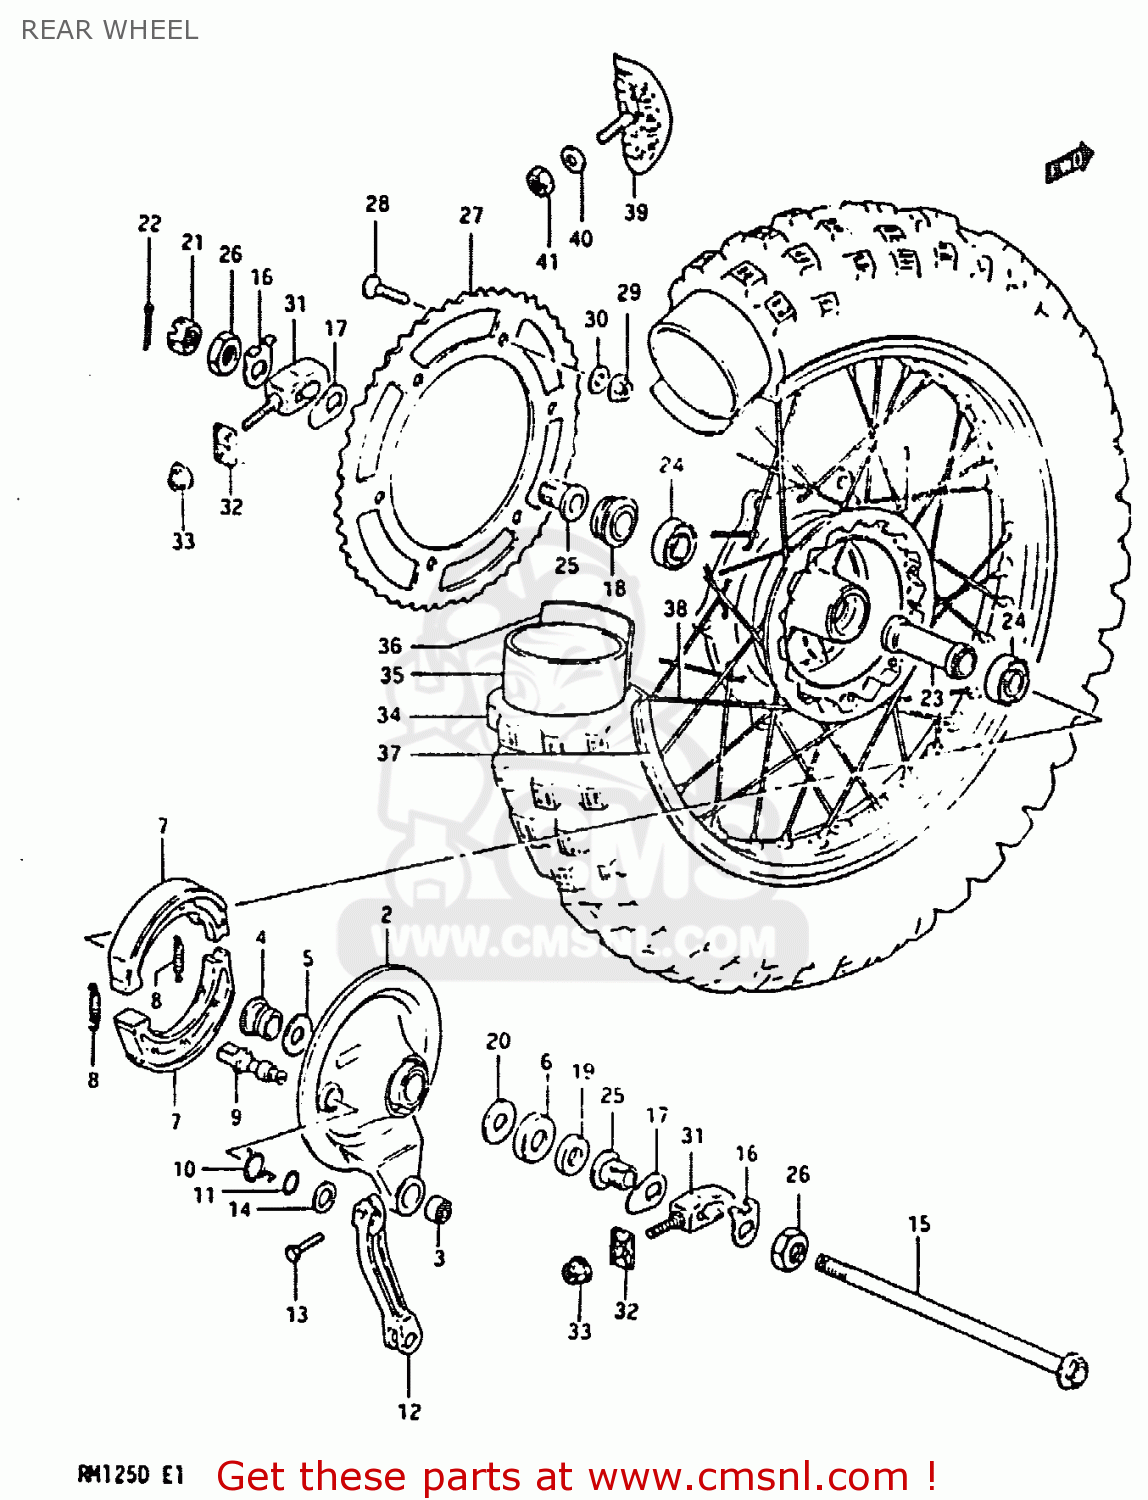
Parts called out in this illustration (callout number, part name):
1	DRUM,REAR HUB
2	PANEL SET,REAR HUB
3	SPHERICAL BRNG,TORQUE LINK
4	SPACER,RR BRAKE ANCHOR PANEL
5	SEAL,OIL(20X27X5)
6	CVR,RR BRAKE AHR PNL DUST SEAL
7	SHOE,BRAKE (MCA)
8	SPRING(L:34)
9	CAM,FR BRAKE
10	SPRING
11	O RING(D:2.5,ID:11.4)
12	LEVER,RR BRAKE CAM
13	BOLT
14	WASHER(12.5X20X1)
15	AXLE,REAR
16	WASHER,CHAIN ADJUSTER GUIDE
17	WASHER,CHAIN ADJUST GUIDE
18	SPACER,RR AXLE,L
19	SPACER,REAR AXLE,RIGHT
20	WASHER,THRUST
21	NUT
22	COTTER PIN
23	SPACER
24	BEARING
25	SPACER,CHAIN ADJUSTER
26	NUT
27	SPROCKET,REAR
28	SCREW(8X33.5)
29	NUT
30	WASHER
31	ADJUSTER,CHAIN
32	PLATE,CHAIN ADJUSTER GUIDE,R
33	NUT
34	TIRE
35	TUBE ASSEMBLY,WHEEL,INNER
36	PROTECTOR,INNER TUBE
37	RIM,REAR WHEEL
38	SPOKE SET,REAR WHEEL
39	STOPPER,BEAD
40	WASHER
41	NUT
